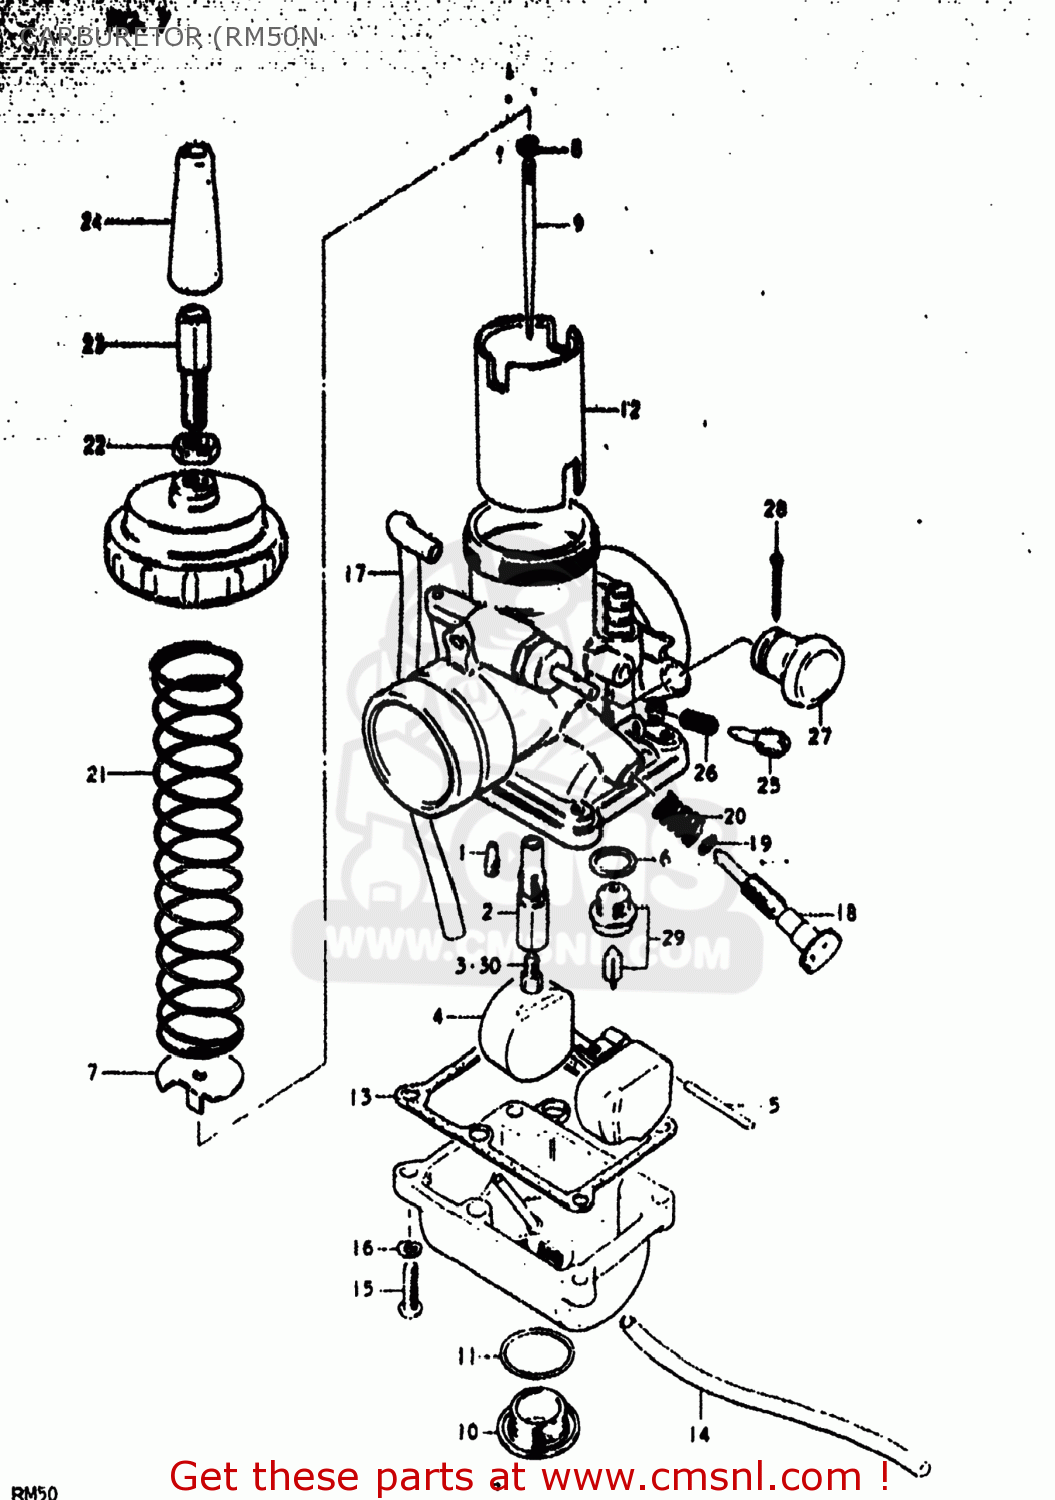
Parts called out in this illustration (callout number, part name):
1	JET,PILOT (17.5)
2	JET,NEEDLE
3	JET, MAIN
4	FLOAT
5	PIN,FLOAT
6	GASKET,NEEDLE VALVE (NAS)
7	STOPPER,NEEDLE CLIP
8	CLIP
9	NEEDLE JET
10	SCREW,GUIDE
11	O-RING
12	VALVE,THROTTLE
13	GASKET,FLOAT CHAMBER (NAS)
14	HOSE
15	SCREW
16	LOCK WASHER
17	HOSE
18	ADJUSTER
19	O-RING
20	SPRING
21	SPRING,THROTTLE VALVE
22	NUT
23	ADJUSTER
24	CAP,CABLE ADJUSTER
25	SCREW,PILOT AIR
26	SPRING
27	LEVER
28	COTTER PIN
29	VALVE ASSY,NEEDLE
30	JET
